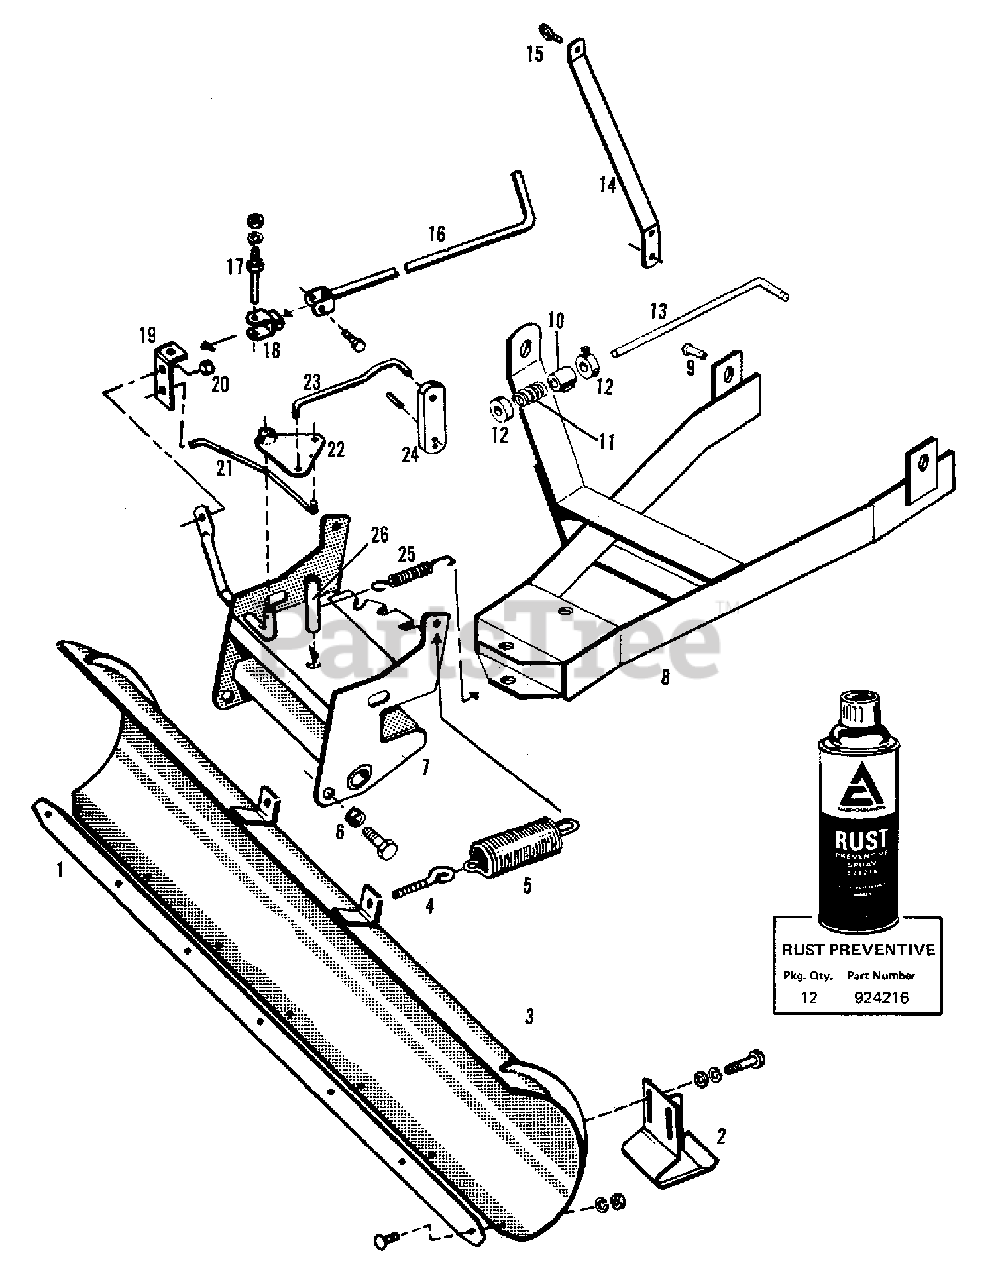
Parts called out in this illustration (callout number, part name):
1	PLATE, Wear
1	BOLT, 3/8NC x 1
1	LOCKWASHER, 3/8
1	NUT, 3/8NC
2	SHOE ASSEMBLY, Blade
2	CAPSCREW, 3/8NC x 3/4
2	LOCKWASHER, 3/8
2	WASHER, 3/8
3	BLADE ASSEMBLY, 46" Width
4	BOLT, Carriage
4	NUT, 5/16NC
7	FRAME ASSEMBLY, Pivot
7	CAPSCREW, 1/2NC x 1-1/2
7	NUT, 1/2 NC, Lock
8	BAR ASSEMBLY, Push
9	PIN, Hitch
9	PIN, Hair Clip
10	GUIDE ASSEMBLY, Rod
12	SETSCREW, 5/16NC x 1/2, GR8 (Square Head Cup Point)
12	WASHER, 17/32 x 1-1/4 x 16 Ga.
13	PIN, Hair Clip
14	BRACKET, Handle
14	CAPSCREW, 3/8NC x 7/8
14	LOCKWASHER, 3/8
14	NUT, 3/8NC
15	BOLT, Eye
15	NUT, 1/4, Lock
16	ROD ASSEMBLY, Angle Adjustment
16	CAPSCREW, 5/16NC x 1-1/2
16	NUT, 5/16NC, Lock
17	STUD, Pivot
17	LOCKWASHER, 5/16
17	NUT, 5/16NC
17	PIN, Hair Clip
18	FORK ASSEMBLY, Adjustment Handle
19	ARM, Pivot
20	CAPSCREW, 5/16NC x 1
20	WASHER, 5/16, Plain
20	LOCKWASHER, 5/16
20	NUT, 5/16NC
21	ROD ASSEMBLY, Pivot
21	PIN, Cotter, 3/32 x 1
22	PLATE ASSEMBLY, Pivot
22	PIN, Cotter, 1/8 x 1
23	ROD, Latch
23	PIN, Cotter, 3/32 x 1
24	LATCH, Pivot
24	PIN, Roll, 7/32 x 1
25	SPRING, LATCH
26	PIN, Pivot
26	PIN, Cotter, 3/16 x 2
